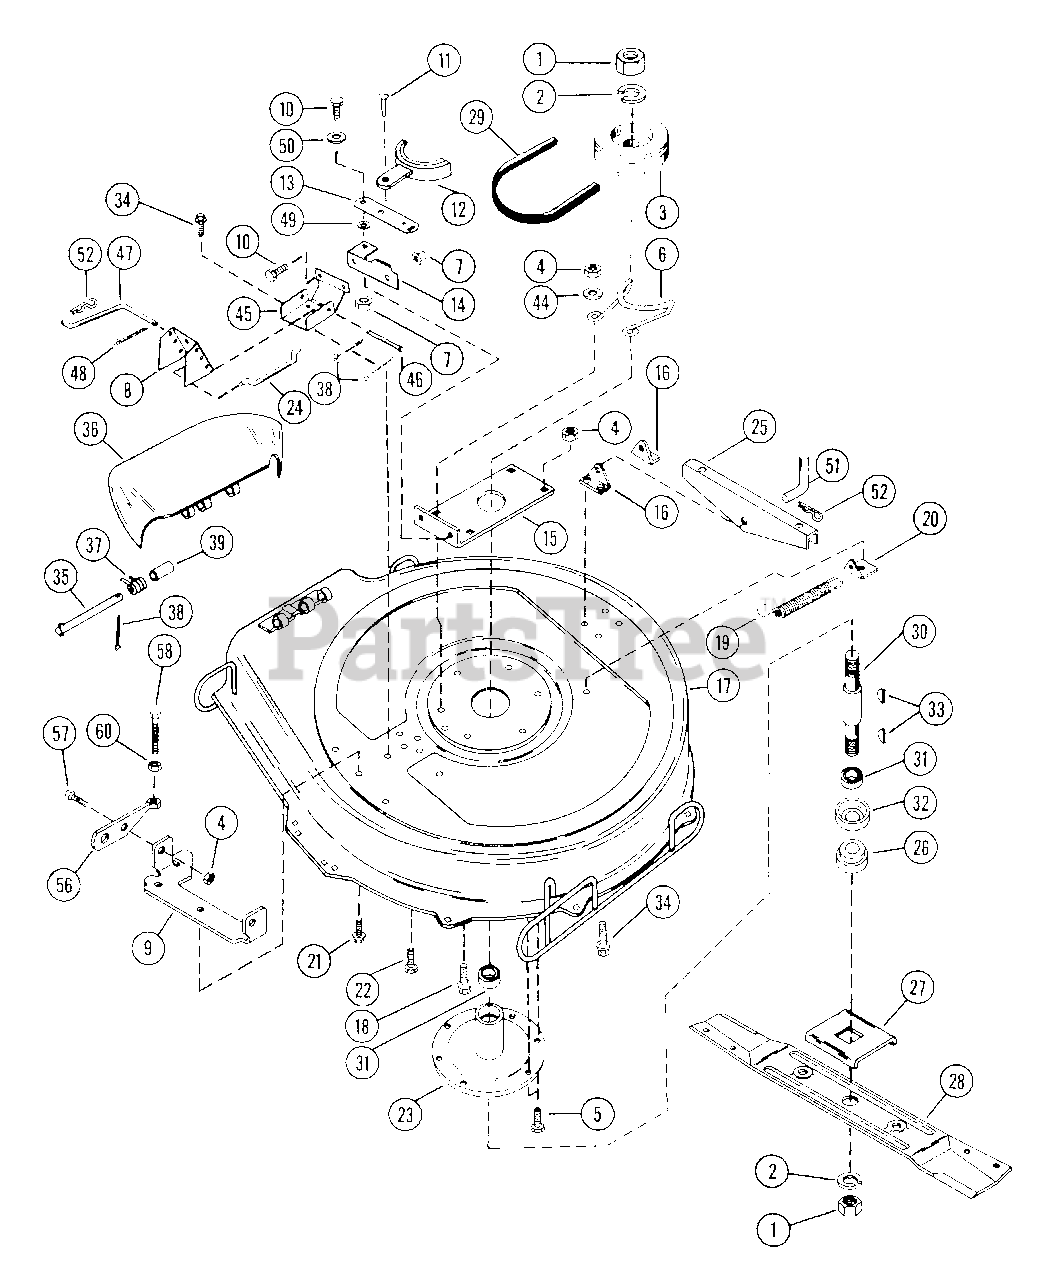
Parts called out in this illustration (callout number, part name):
1	NUT-JAM .75-10 PL
2	WSHR-LK .750X.188 MED PL
3	MOWER SHEAVE
4	NUT-LK-CTR .375-16 GR A PL
5	BLT-HEX .38-16X1.00 PL
6	MOWER BELT FINGER
7	NUT-LK .312-18 GR A PL
8	MOWER ENGAGING ARM
9	FRONT BRACKET 30"
10	BLT-HEX .31-18X.63 PL GR 2
11	RVT .25X.50 RH ST
12	BLADE BRAKE
13	MOWER BRAKE LEVER
14	BRAKE BRACKET
16	REAR MOUNTING BRACKET
17	30"MOWER PAN W/DEFLECTOR&DECAL
18	BLT-SERHFWH .25-20X.50 PL
19	SG-TENS .072X.51X5.31 WLD 25
20	BRAKE CLIP
21	BLT-SCRHFWH .38-16X.50 PL
22	BLT-HEX .31-18X.50 PL GR2
23	SPINDLE HOUSING
24	MOWER BRAKE LINK
25	SWIVEL BRACKET
26	RETAINER HUB
27	BLADE TRAY
28	MOWER BLADE 30 INCHES
29	V-BELT
30	SPINDLE SHAFT
31	BRG-BALL .750X1.781X.61
32	BEARING SLINGER
33	KEY-WDRF .188X.75X.313 SAE 9
34	BLT-SERHFWH .31-18X.50 PL
35	CLEVIS PIN
36	PAN CHUTE EXTENSION
37	SG-TORS .095X.50X 1.0
38	PIN-COTR .09X.75 PL
39	BSHG-SLV .334 X .502 X 1.437
44	WSHR-FL-STL .406X.865X.094 PL
45	PIVOT BRACKET
46	PIN-CLEV .309X3.50 SP
47	MOWER ENGAGEMENT LINK
48	PIN-COTR .12X.75 PL
49	SPACER BUSHING .5 X .32 X .163
50	WSHR-FL-STL .328X1.0X.094
51	CLEVIS PIN
52	PIN-HAIR INT .08X.38X1.42 YWZC
56	ADJUSTING ARM
57	@BLT-HEX .38-16X.88 PL GR2
58	BLT-HEX .38-16X1.25 PL GR5
60	NUT-JAM .375-16 PL
